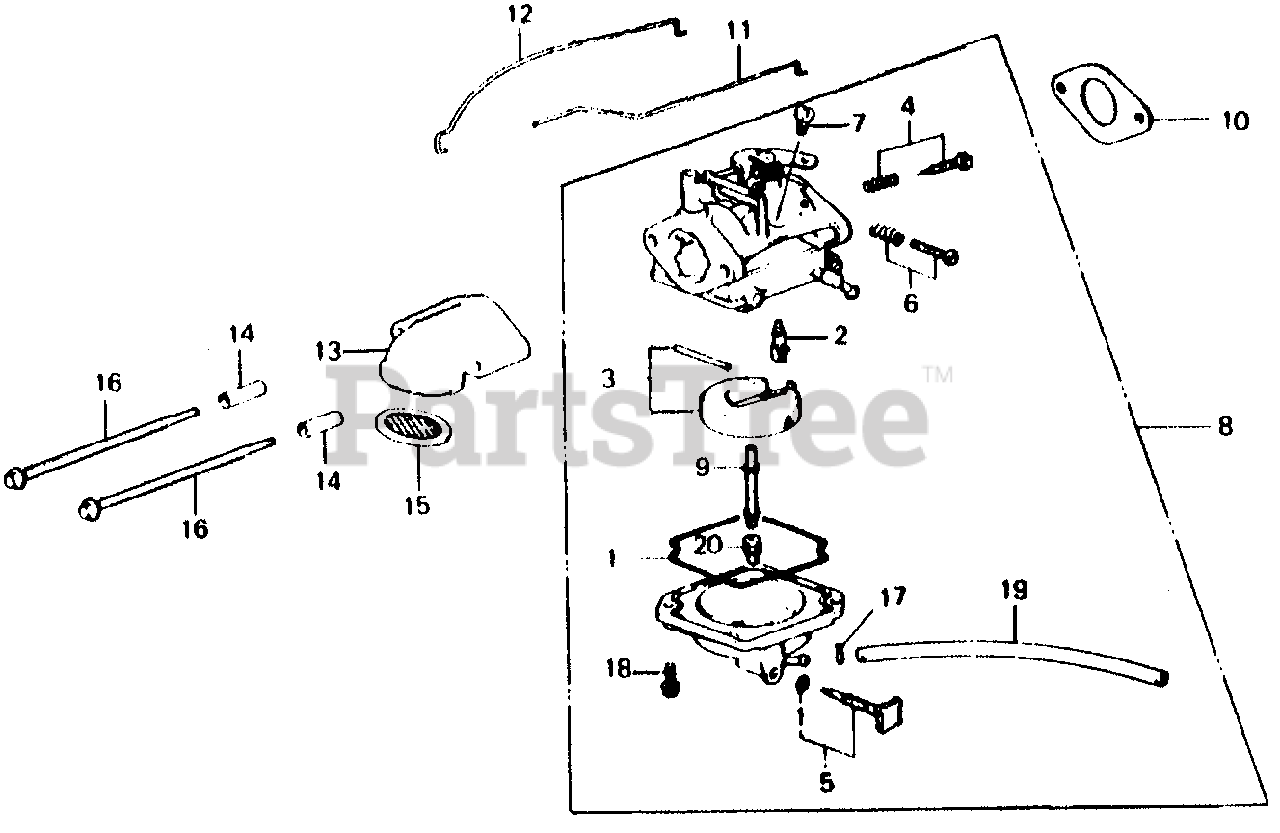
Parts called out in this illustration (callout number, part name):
1	GASKET SET
2	VALVE SET, FLOAT
3	FLOAT SET
4	SCREW SET A
5	SCREW SET, DRAIN
6	SCREW SET B (N/A: SEE ASSEMBLY)
7	SCREW, PLUG (NOT AVAILABLE)
8	CARBURETOR ASSY.
9	NOZZLE, MAIN (N/A: SEE ASSEMBLY)
10	GASKET, CARBURETOR
11	ROD, THROTTLE
12	ROD, CHOKE
13	GUIDE, AIR
13	GUIDE, AIR (NOT AVAILABLE)
14	COLLAR, DISTANCE
15	TRAP, FLAME
16	BOLT, FLANGE (6X97)
17	CLIP B7, TUBE
18	SCREW-WASHER (4X12)
19	BULK HOSE, FUEL (3.5X3000) (3.5X140)
20	JET, MAIN (#72)
20	JET, MAIN (#78)
20	JET, MAIN (#80)
20	JET, MAIN (#82)
20	JET, MAIN (#88)
